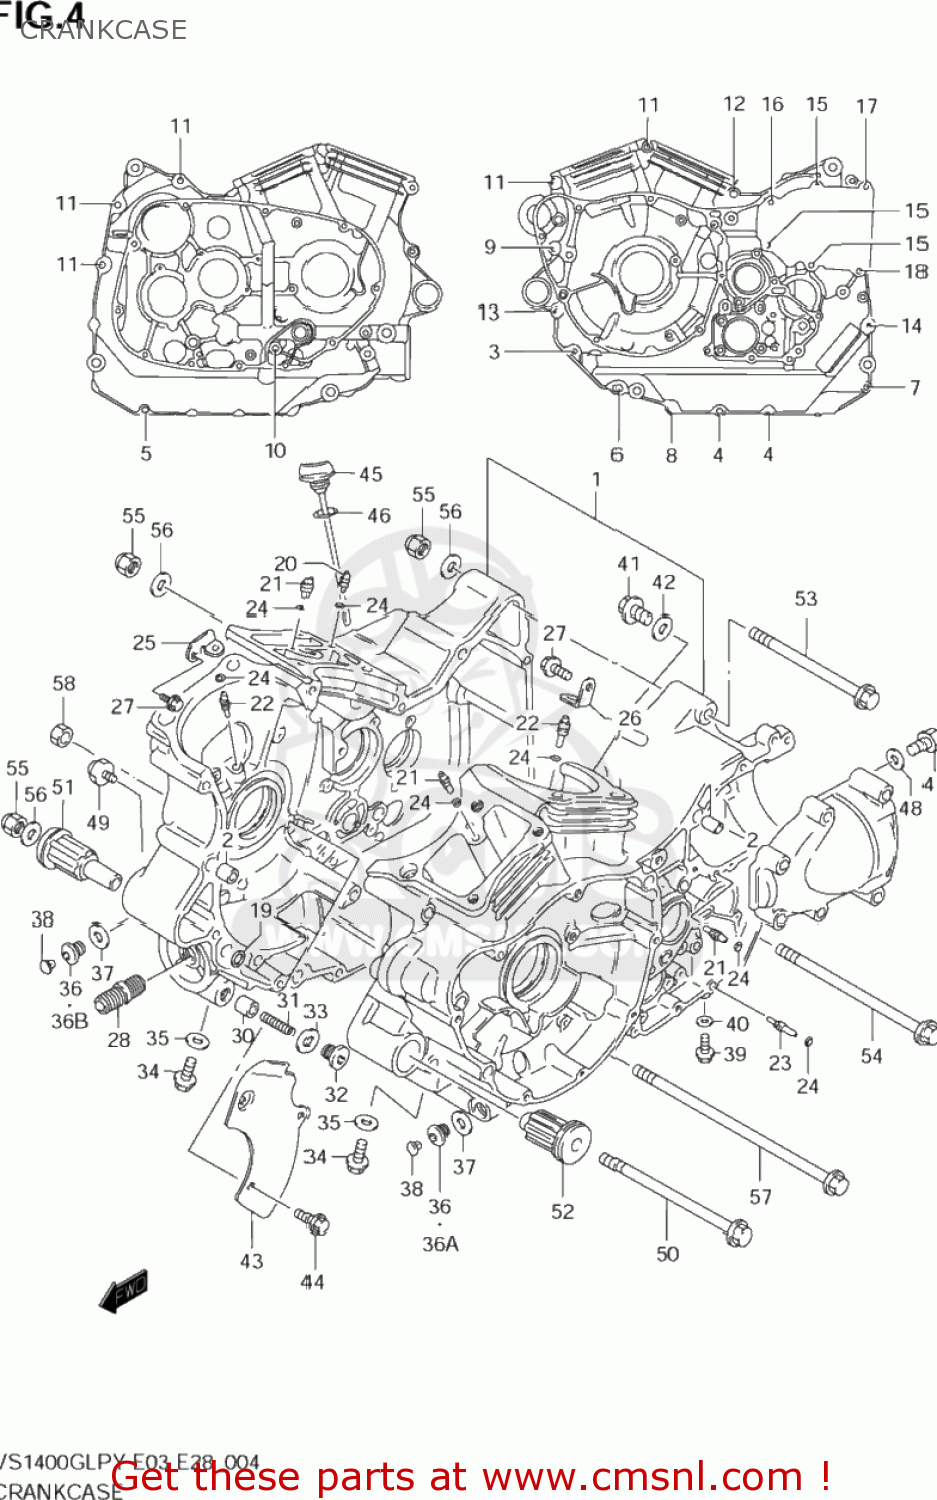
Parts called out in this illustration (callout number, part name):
1	CRANKCASE SET
2	PIN(8.4X11X20)
3	BOLT
4	BOLT
5	BOLT
6	BOLT
7	BOLT
8	BOLT(8X70)
9	BOLT
10	BOLT(8X115)
11	BOLT(8X95)
12	BOLT(8X50)
13	BOLT(8X70)
14	BOLT(8X80)
15	BOLT
16	BOLT
17	BOLT
18	BOLT
19	O RING(D:1.9,ID:12.6)
20	JET(2.2)
21	JET,AIR(14)
22	JET,PISTON COOLING(0.8)
23	JET,MISSION OIL(1.4)
24	O RING(D:1.2,ID:4)
25	PLATE,PISTON JET FR
26	PLATE,PISTON JET RR
27	BOLT
28	UNION,OIL STAND
29	PLATE,CRANK THRUST
30	PLUNGER,OIL CONTROLL
31	SPRING
32	PLUG
33	GASKET(16X22X2) (NAS)
34	BOLT
35	GASKET(8.2X14X1).6 (NAS)
36	PLUG,14X12
36A	PLUG,14X12
36B	PLUG(14X11.5)
37	GASKET(13.8X18.8X4.8) (NAS)
38	CAP(OD:12)
39	BOLT
40	GASKET(5.8X11X1.2) (NAS)
41	PLUG(12X10)
42	GASKET(12.1X16.2X3.7) (NAS)
43	PLATE,OIL SEPARATOR
44	BOLT
45	GAUGE,OIL LEVEL
46	O RING(D:3.1,ID:16.8)
47	BOLT
48	GASKET(12.1X16.2X3.7) (NAS)
49	SWITCH ASSY,OIL PRESSURE
50	BOLT(10X155)
51	BUSH,ENGINE MOUNTING,R
52	BUSH,ENGINE MOUNTING
53	BOLT(10X135)
54	BOLT(10X180)
55	NUT
56	WASHER
57	BOLT(10X225)
58	NUT
